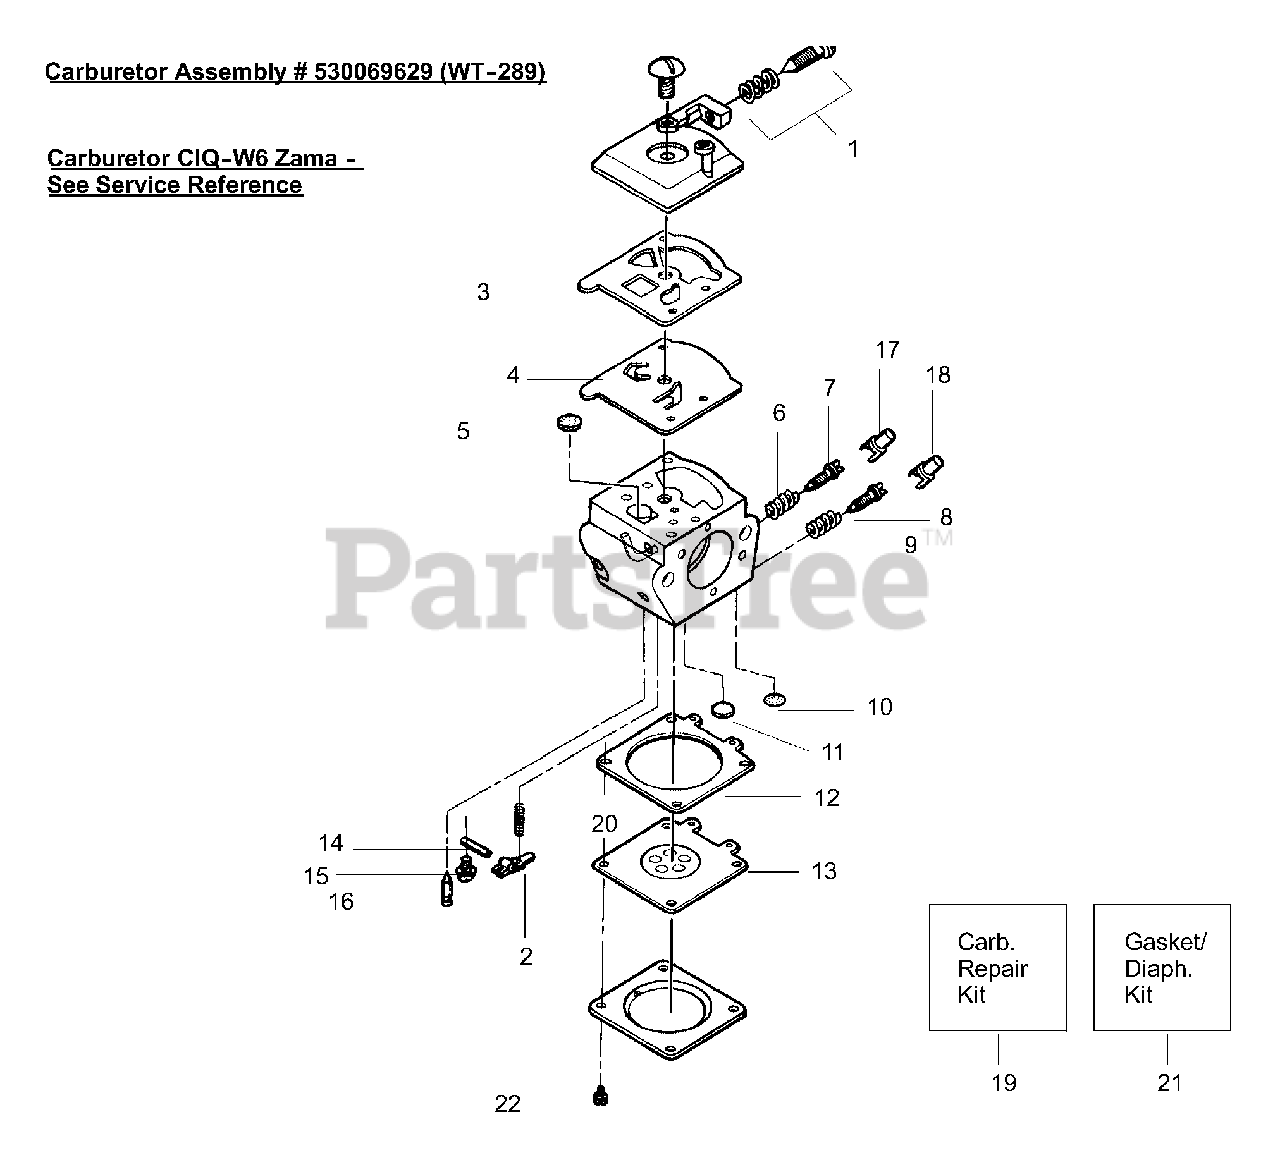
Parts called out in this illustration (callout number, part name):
1	Idle Adv. Screw Kit
2	Metering Lever
3	Fuel Pump Gasket
4	Fuel Pump Diaphragm
5	Fuel Inlet Screen
6	Needle Spring (Low Speed)
7	Low Speed Needle
8	High Speed Needle
9	Needle Spring (High Speed)
10	Welch Plug (5/16)
12	Metering Diaphragm Gasket
13	Metering Diaphragm
14	Metering Lever Pin
15	Metering Lever Pin Screw
16	Inlet Needle Valve
17	Limiter Cap High
18	Limiter Cap Low
19	Walbro Carburetor Repair Kit
19	Zama Carburetor Repair Kit
20	Metering Lever Spring
21	Walbro Gasket/Diaphragm Kit
21	Zama Gasket/Diaphragm Kit
22	Metering Cover Screw Ass'y
530069629	Carburetor Assembly WT-289
